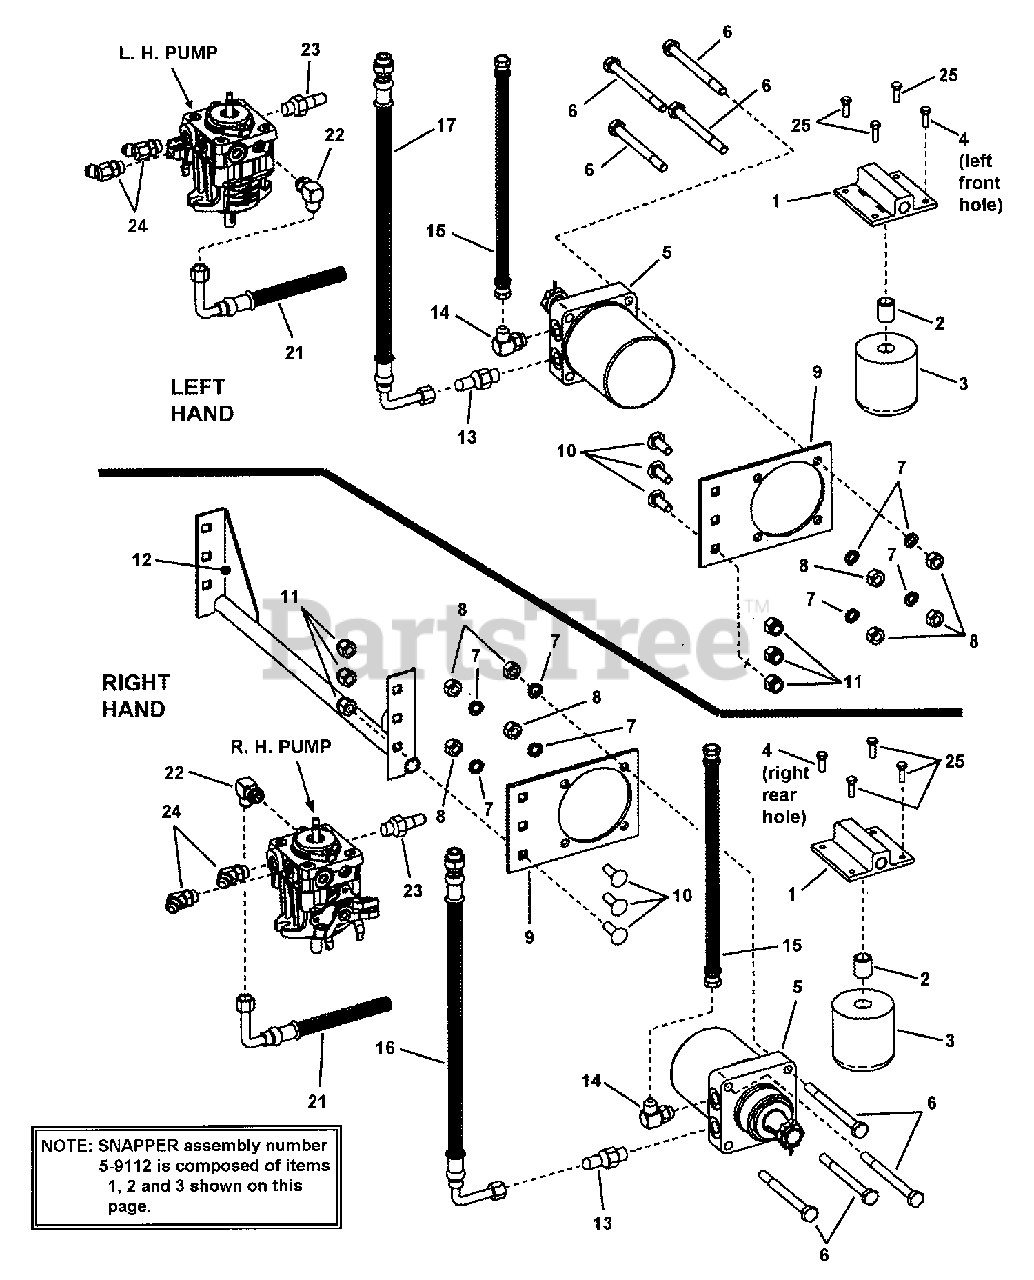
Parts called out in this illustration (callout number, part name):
1	MOUNT, Oil Filter
2	FITTING, Straight 1-12 UNF Thread
3	FILTER, Oil
4	SCREW, 3/8-16 x 3/4" Hex Washer Self-Tap
5	MOTOR, Hydraulic
6	BOLT, 1/2-13 x 6" Hex Head Cap GR5
7	WASHER, 1/2" Split Lock
8	NUT, 1/2-13 HEX
9	PLATE, Mounting
10	BOLT, 1/2-13 x 1-1/2" Square Neck Carriage GR5
11	NUT, 1/2-13 Hex Nyloc
12	WELDMENT, Rear Crossbrace
13	CONNECTOR, Straight Hydraulic (Parker # 8-10 F5OLO-S)
14	CONNECTOR, 90 Degree Hydraulic (Parker # 8-10 C5OLO-S)
15	HOSE, 13-3/4" Hydraulic (Parker # F436BKJCJC080808-13-75)
16	HOSE, 19-1/2" Hydraulic (Parker # F436BKJCJ5080808-19.5)
17	HOSE, 17-1/2" Hydraulic (Parker # F436BKJCJ5080808-17.5)
21	HOSE, 6-1/2" (Parker # R836BKJ9NR080008-6.5
22	CONNECTOR, 90 Degree Hydraulic (Parker # 8-6 C5OLO-S
23	CONNECTOR, Straight Hydraulic (Parker # 8-6 F5OLO-S)
24	CONNECTOR, 45 Degree Hydraulic (Parker # V5OLO-S)
25	SCREW, 5/16-18 x 3/4" Hex Washer Self-Tap
